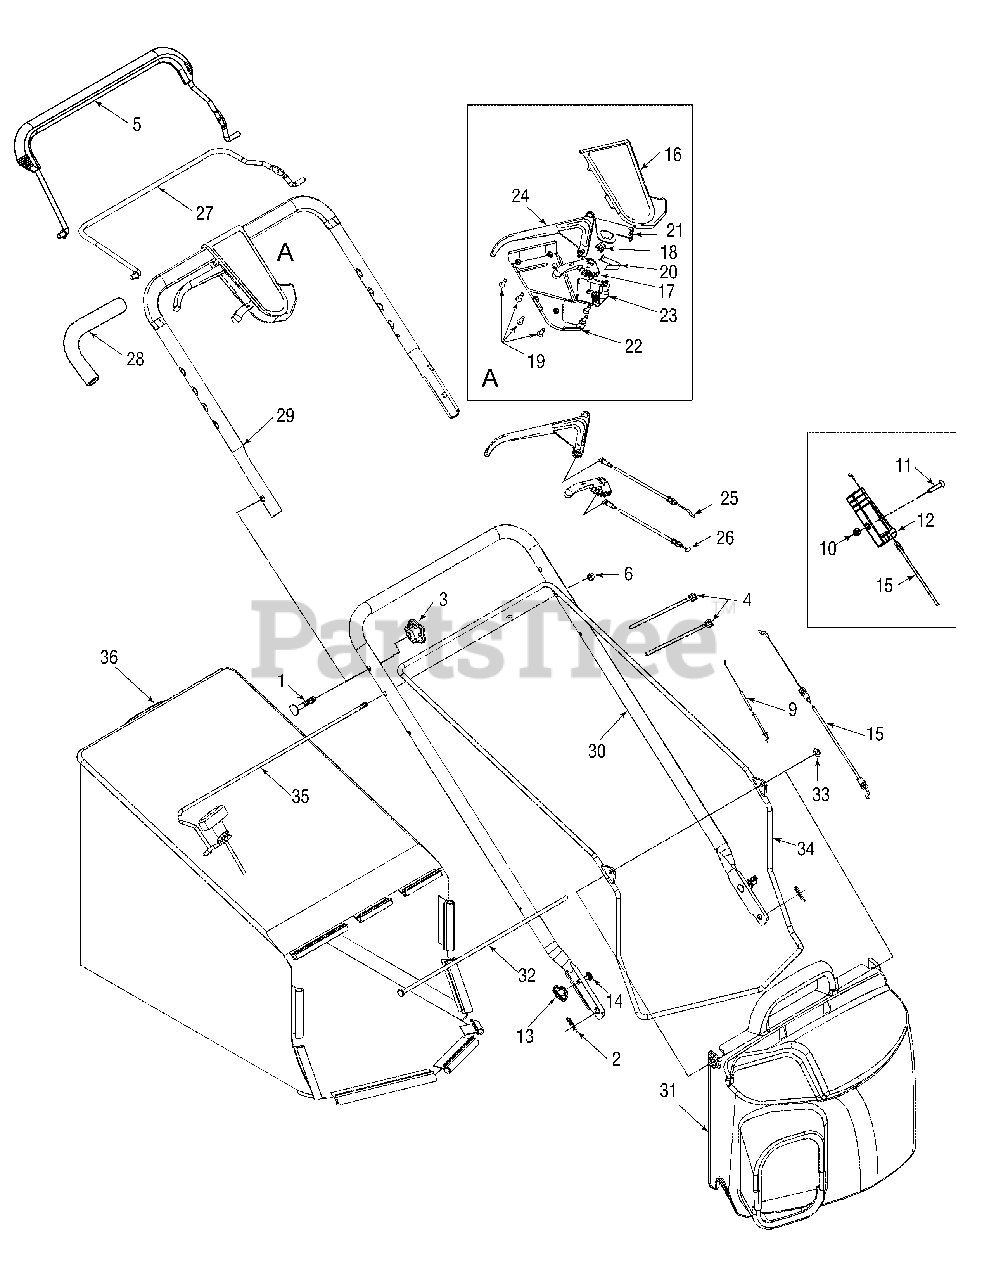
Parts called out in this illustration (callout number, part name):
1	Carriage Bolt 5/16-18 x 2.0
2	Int. Cotter Pin 5/16 DIA
3	Plastic Knob
4	Cable Tie
5	Control Bail Lever - Deluxe Black
5	Control Bail Lever - Red
5	Control Bail Lever - Grey
6	Flg. Lock Nut 5/16-18 Gr. F Nylon
8	Cup. Wash. .265 ID x .75 OD x .062
9	Throttle Wire 60.0" Lg. Yellow
10	Hex Ins. Locknut 1/4-20
11	Mach. Scr. 1/4-20 x 1.319
12	Cable Bracket
13	Carriage Bolt 1/4-20 x .75
14	Wing Nut
15	Control Cable 47.0" Lg.(Honda)
16	Control Cover
17	6 Speed Shift Lever
18	3 Tooth Rack Gear Insert
19	C-sunk Tap Screw #10 x .75
20	Shift Lever Spring
21	Rack Cable Bracket
22	Control Cover
23	Control Cover
24	Control Lever
25	Pulley Cable 53" Lg.
26	Clutch Cable - 53" Lg. Orange
28	Foam Grip
31	Grassbag Cover w/Label
32	Grasscatcher Pivot Rod
36	Grassbag
